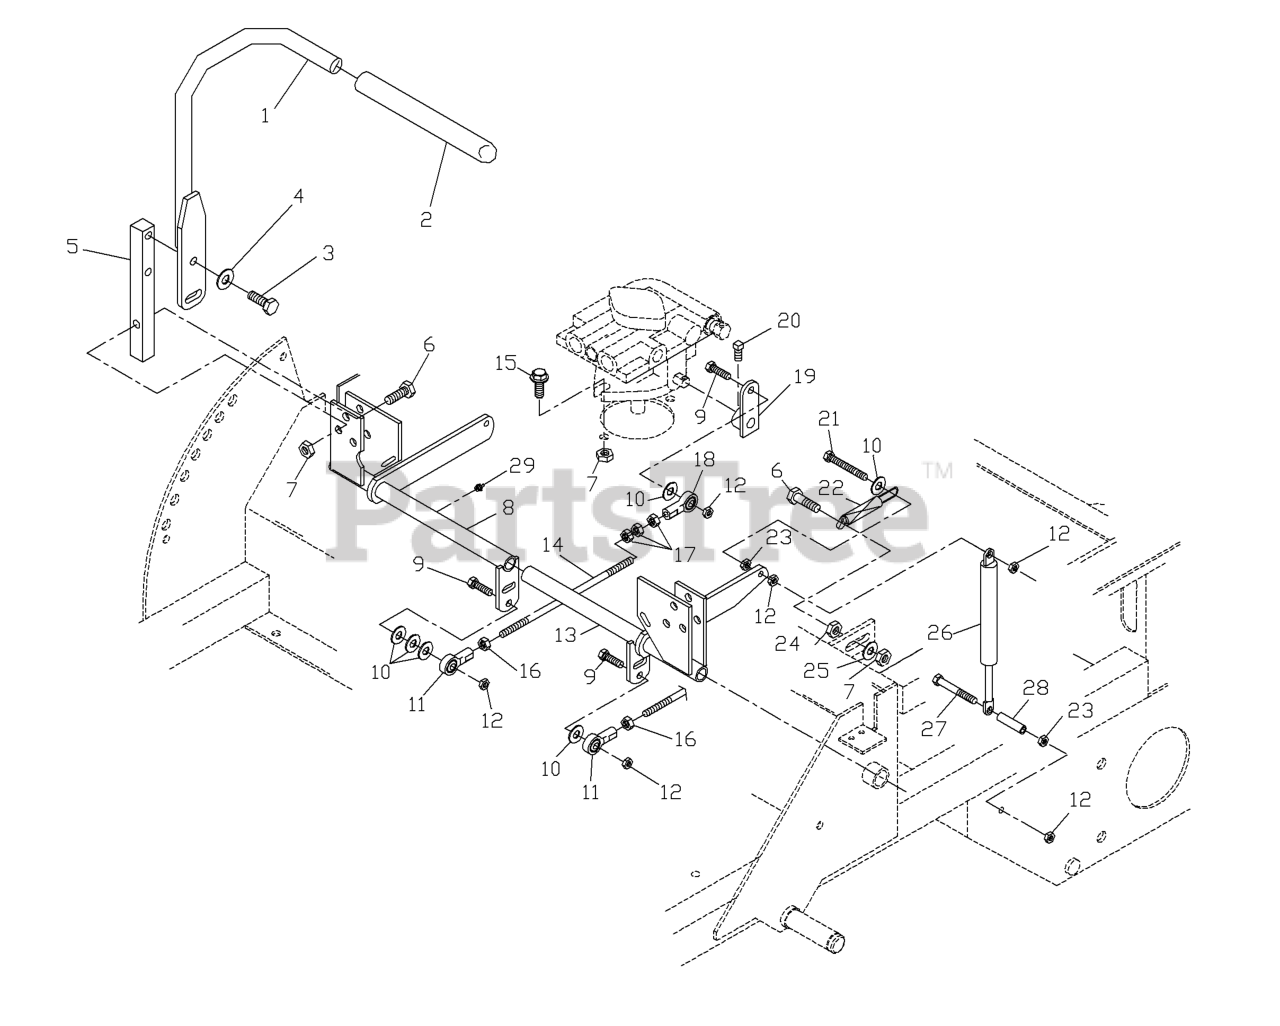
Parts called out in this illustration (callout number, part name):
1	CONTROL LEVER WELDMENT
3	HCS 3/8-16X1.GRD.5.ZD
4	WASHER, 3/8 DISC SPRING SPEC
5	CONTROL ARM
6	HCS 3/8C X 1 1/2
7	NUT 3/8C CENTERBLOCK
8	CONTROL WELDMENT, RIGHT
9	HCS 5/16C X 1 1/4
10	WASHER 5/16 FLAT
11	BALL JOINT, LEFT HANDED
12	NUT 5/16C CENTERLOCK
13	CONTROL WELDMENT, LEFT
14	PUMP CONTROL LINK
15	4CS 3/8C X 1 SERRATED HEAD
16	NUT 5/16F LEFTHAND
18	BALL JOINT, RIGHT HANDED
19	PUMP LEVER
20	SCREW 5/16C X 5/8 SQ HEAD
21	TAP BOLT 5/16C X 2 1/4
23	NUT 5/16C WHIZ
24	NUT 3/8C WHIZ
25	WASHER 3/8 FLAT
27	HCS 5/16C X 2 3/4 GRADE 8
29	ZERK
